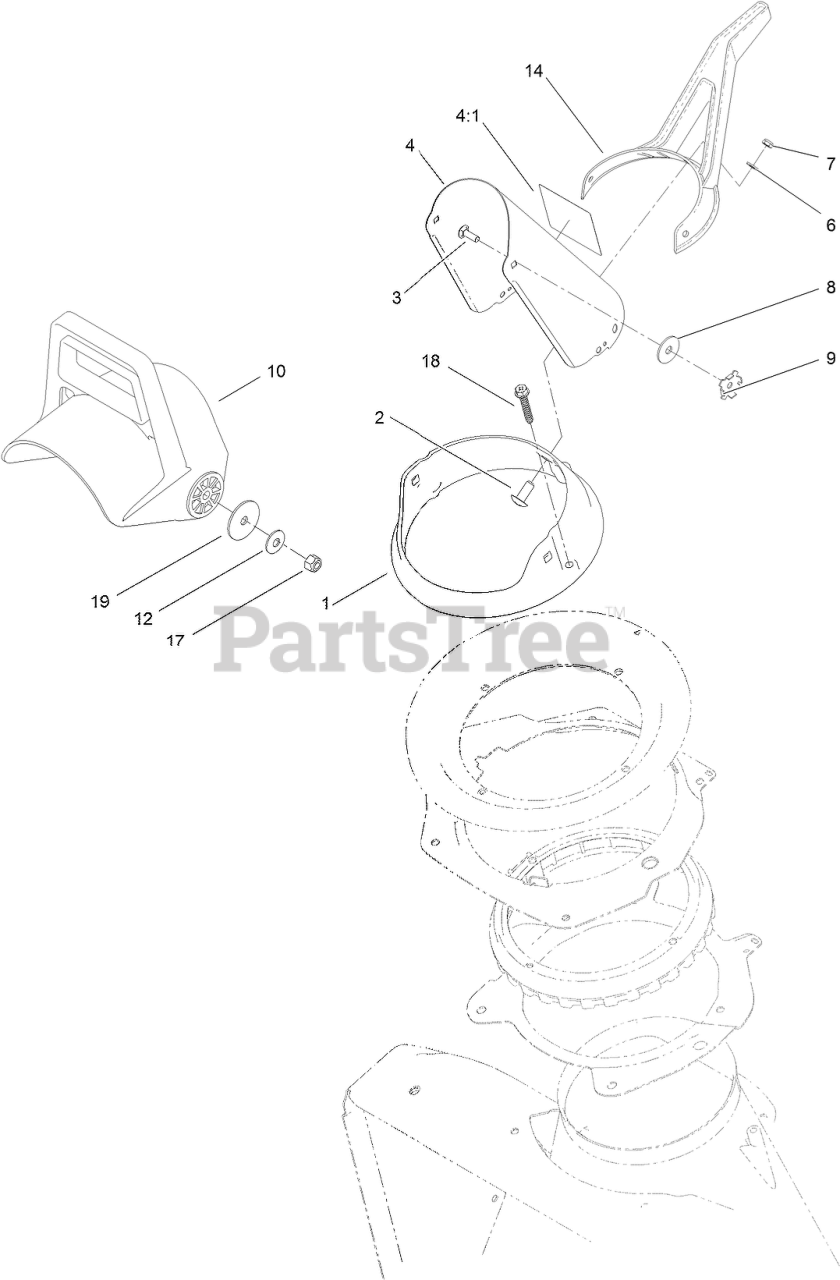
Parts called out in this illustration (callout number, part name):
1	RING-CHUTE
2	SCREW-PTH
3	SCREW-CARR
4	DISCHARGE CHUTE ASM
4:1	DECAL-DANGER, CE
6	WASHER-FLAT
7	NUT-LOCK, NI
8	WASHER-RUBBER
9	PLATE-FRICTION
10	CHUTE-DEFLECTOR
12	WASHER-BELLEVILLE
14	HANDLE-CONTROL, CHUTE
17	NUT-LOCK, NI
18	SCREW-PLASTITE
19	WASHER-FLAT
